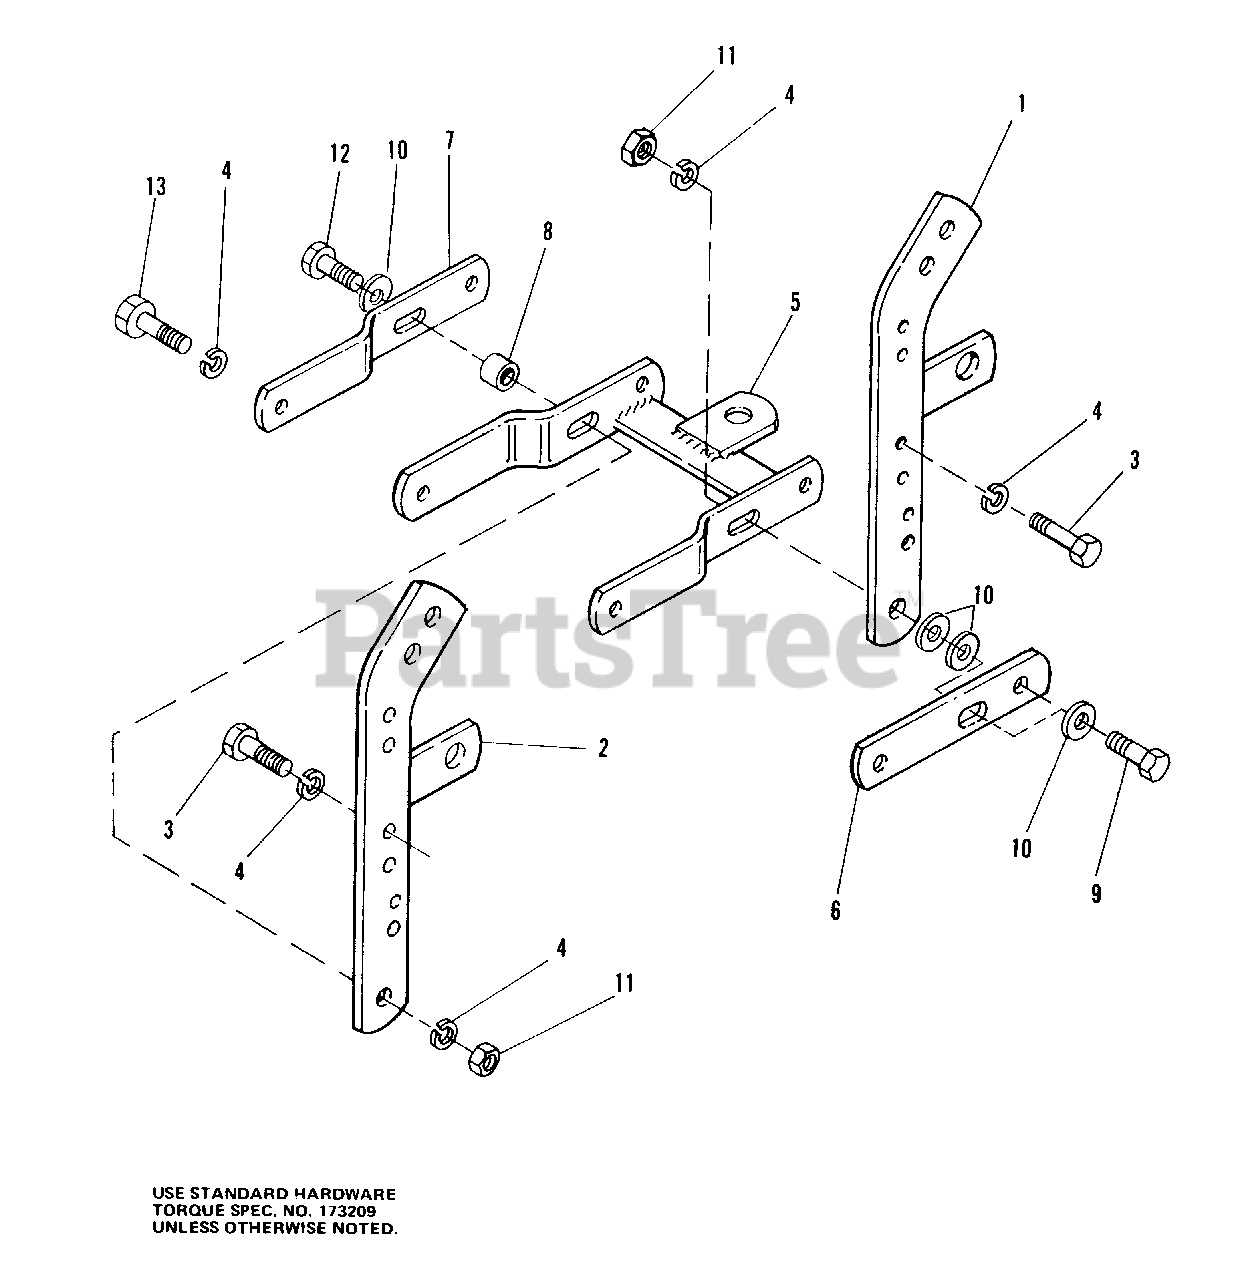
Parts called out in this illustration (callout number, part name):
1	L.H. ARM ASSEMBLY
2	R.H. ARM ASSEMBLY
3	CAPSCREW, Hex Hd., 7/16-14 x 1
4	LOCKWASHER, 7/16
5	DRAWBAR ASSEMBLY
6	BAR, Pull, L.H.
7	BAR, Draw, R.H.
9	CAPSCREW, Hex Hd., 7/16-14 x 1-1/4
10	WASHER, 7/16
11	NUT, Hex, 7/16-14
12	CAPSCREW, Hex Hd., 7/16-14 x 2-1/4
13	CAPSCREW, Hex Hd., 7/16-14 x 1-3/4
